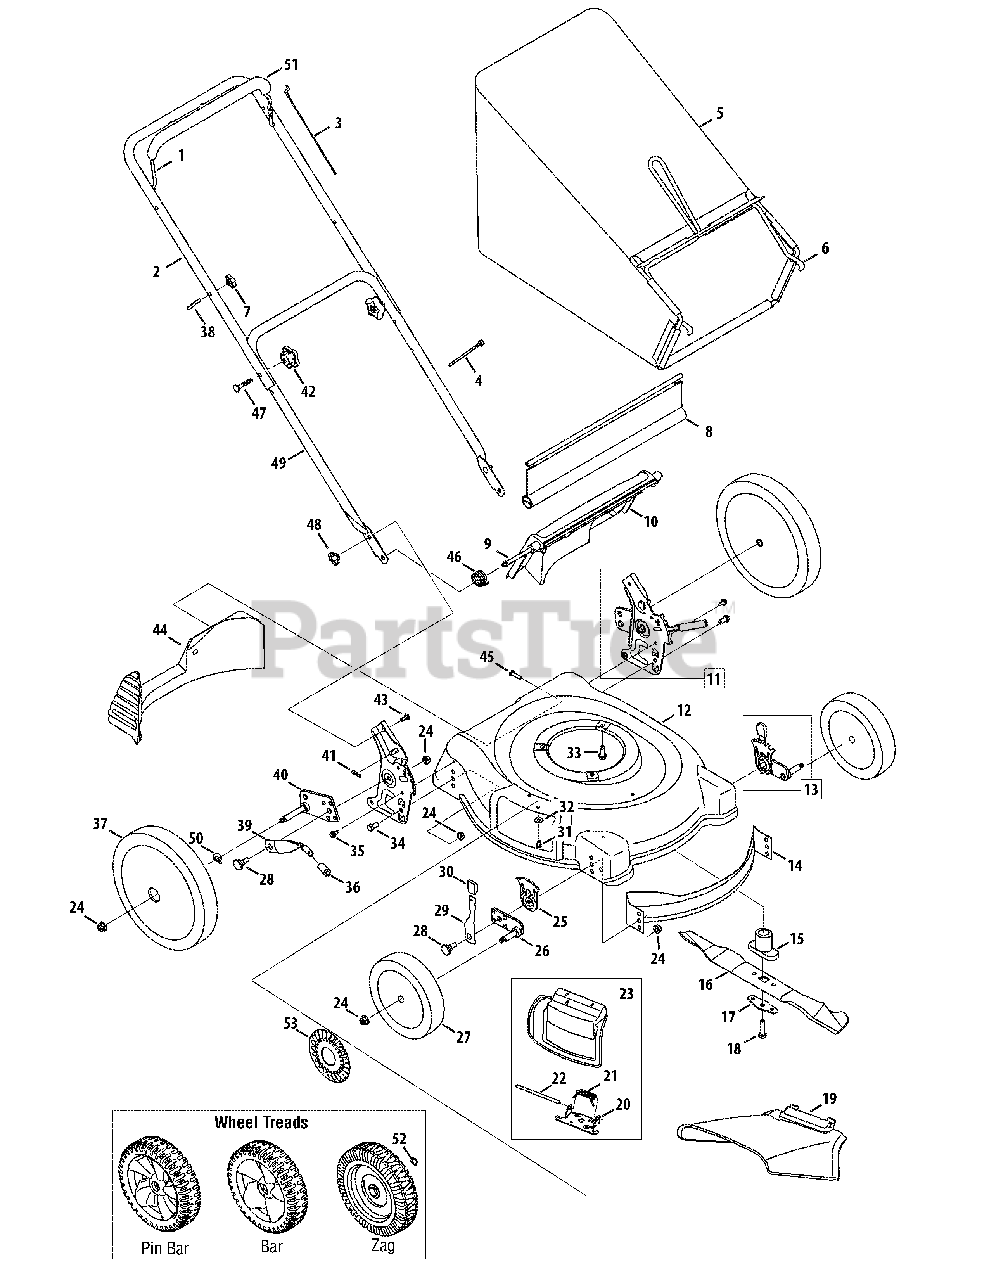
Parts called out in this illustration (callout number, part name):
1	Blade Control
2	Upper Handle
3	Control Cable, 37.25" Briggs & Stratton
3	Control Cable, 40" Honda
3	Control Cable, 48" Kohler
4	Cable Tie
5	Grass Bag - w/o Logo
6	Grass Bag Frame
7	Handle Knob
8	Trail Shield
9	Pivot Rod
10	Rear Discharge Door
11	Rear Handle Bracket Assy. - LH
11	Rear Handle Bracket Assy. - RH
12	Deck 21-inch - Silver Flake
12	Deck 21-inch - Red
12	Deck 21-inch - Black Jack
12	Deck 21-inch - Green
13	Front Hgt. Adj. Assy., 8" Wheel. - LH
13	Front Hgt. Adj. Assy., 8" Wheel. - RH
13	Front Hgt. Adj. Assy., 7" Wheel. - LH
13	Front Hgt. Adj. Assy., 7" Wheel. - RH
14	Front Baffle
15	Blade Adapter, #6 x 2.15
15	Blade Adapter, 25mm - Honda
16	21-inch Mulching Blade
17	Bell Blade Support
18	Hex Screw, 3/8-24 x 2.5
19	Side Discharge Chute
20	Deflector Chute Adaptor
21	Torsion Spring
22	Hinge Pin
23	Mulch Plug Assembly
24	Flange Lock Nut 3/8-16
25	Height Adjustment Plate
26	Pivot Arm Assy LH 7" wheel)
26	Pivot Arm Assy RH (7" wheel)
26	Pivot Arm Assy RH (8" wheel)
26	Pivot Arm Assy LH (8" wheel)
27	Front Wheel, 8" x 1.8, Bar
27	Front Wheel, 7" x 1.8, Bar
27	Front Wheel, 8" x 2.125, Zag
27	Front Wheel, 8" x 2.125, Zag, Yellow
27	Front Wheel, 8" x 1.8, Pin Bar
28	Shoulder Scr., .5D x .385
29	Front Spring Lever
30	Height Adjust Knob
31	TT Screw, 1/4-20 x .500
32	Bell Washer
33	TT Screw, 3/8-16 x 1.0
34	Hex Screw, 3/8-16 x .75
35	TT Screw, 1/4-20 x .625
36	Foam Grip
37	Rear Wheel, 12 x 1.8, Bar
37	Rear Wheel, 12 x 2.125, Zag
37	Rear Wheel, 12 x 2.125, Zag,Yellow
37	Rear Wheel, 12 x 1.8, Pin Bar
38	Eye Bolt
39	Rear Hi-Wheel Spring Lever
40	Rear Pivot Arm Assy - RH
40	Rear Pivot Arm Assy - LH
41	Hairpin Clip
42	Star Knob
43	Carriage Bolt ,1/4-20 x .75
44	Rear Baffle
45	Screw HL, 1/4-15 x 1.00
46	Torsion Spring - RH
47	Carriage Bolt, 5/16-18 x 2
48	Wing Nut
49	Lower Handle
50	Spring Washer
51	Deluxe Bail Cover - Black
51	Deluxe Bail Cover - Gray
52	Wave Washer, .510 x .750 x .017
53	Hub Cap
